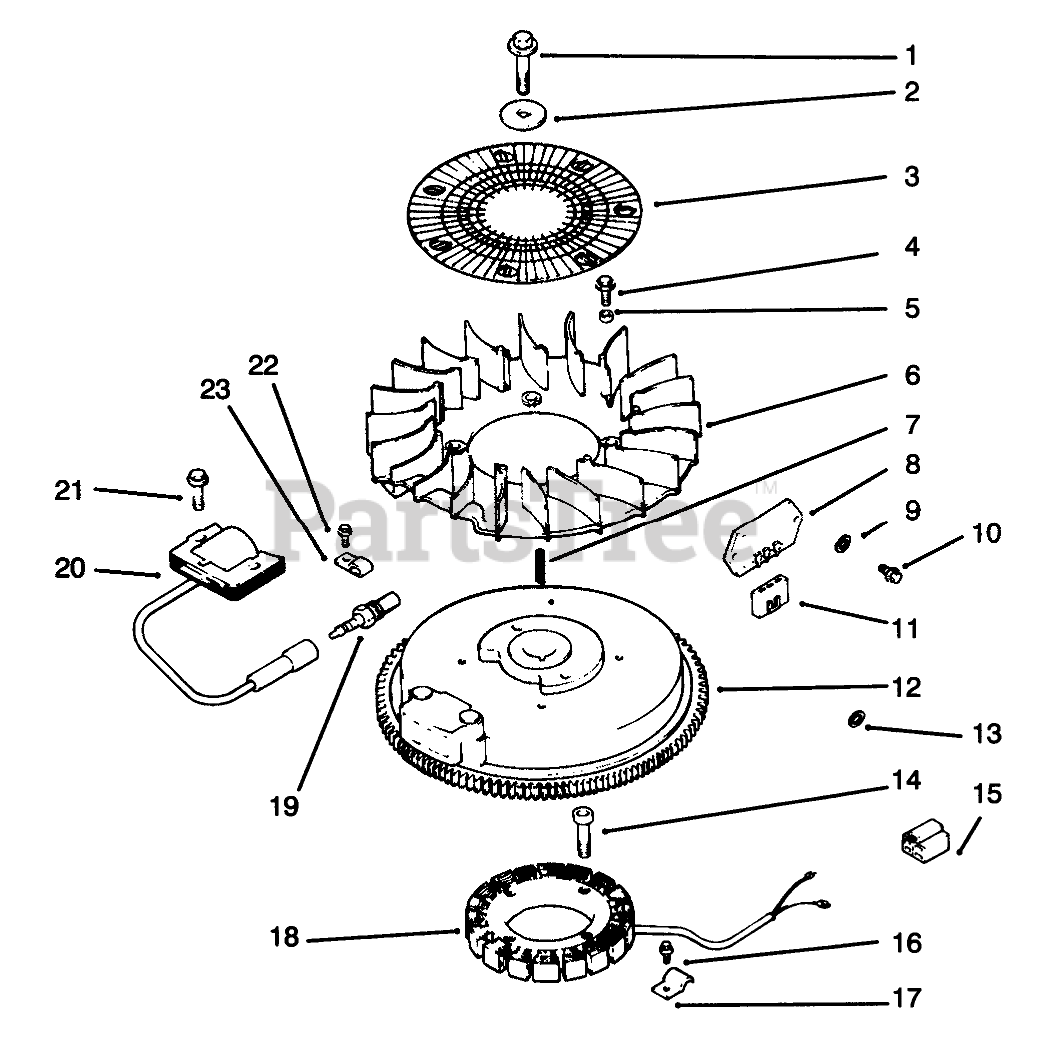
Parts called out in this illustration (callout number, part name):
1	Screw-Flywheel Mounting (Only On: 72042, 72043, 72062, 72063)
2	Washer-Flywheel Screw (Only On: 72042, 72043, 72062, 72063)
3	Screen-Grass (Only On: 72042, 72043, 72062, 72063)
4	Screw M6x1.0x16 (Only On: 72042, 72043, 72062, 72063)
5	Spacer-Fan (Only On: 72042, 72043, 72062, 72063)
6	Fan (Only On: 72042, 72043, 72062, 72063)
7	Key (Only On: 72042, 72043, 72062, 72063)
8	Rectifier-Regulator (Only On: 72042, 72043, 72062, 72063)
9	Washer-Lock (Only On: 72042, 72043, 72062, 72063)
10	Screw M6x1.0x16 (Only On: 72042, 72043, 72062, 72063)
11	Connector-Regulator (Only On: 72042, 72043, 72062, 72063)
12	Flywheel ASM (Only On: 72042, 72043, 72062, 72063)
13	Washer-Flat (Only On: 72042, 72043, 72062, 72063)
14	Screw M5x0.8x25 (Only On: 72042, 72043, 72062, 72063)
15	Connector-5 Contact (Only On: 72042, 72043, 72062, 72063)
16	Screw M5x0.8x10 (Only On: 72042, 72043, 72062, 72063)
17	Clip-Stator Harness (Only On: 72042, 72043, 72062, 72063)
18	Stator-15 Amp (Only On: 72042, 72043, 72062, 72063)
19	Spark Plug (Only On: 72042, 72043, 72062, 72063)
20	Module-Ignition (Only On: 72042, 72043, 72062, 72063)
21	Screw M5x0.8x20 (Only On: 72042, 72043, 72062, 72063)
22	Screw M5x0.8x10 (Only On: 72042, 72043, 72062, 72063)
23	Clip-Kill Lead (Only On: 72042, 72043, 72062, 72063)
